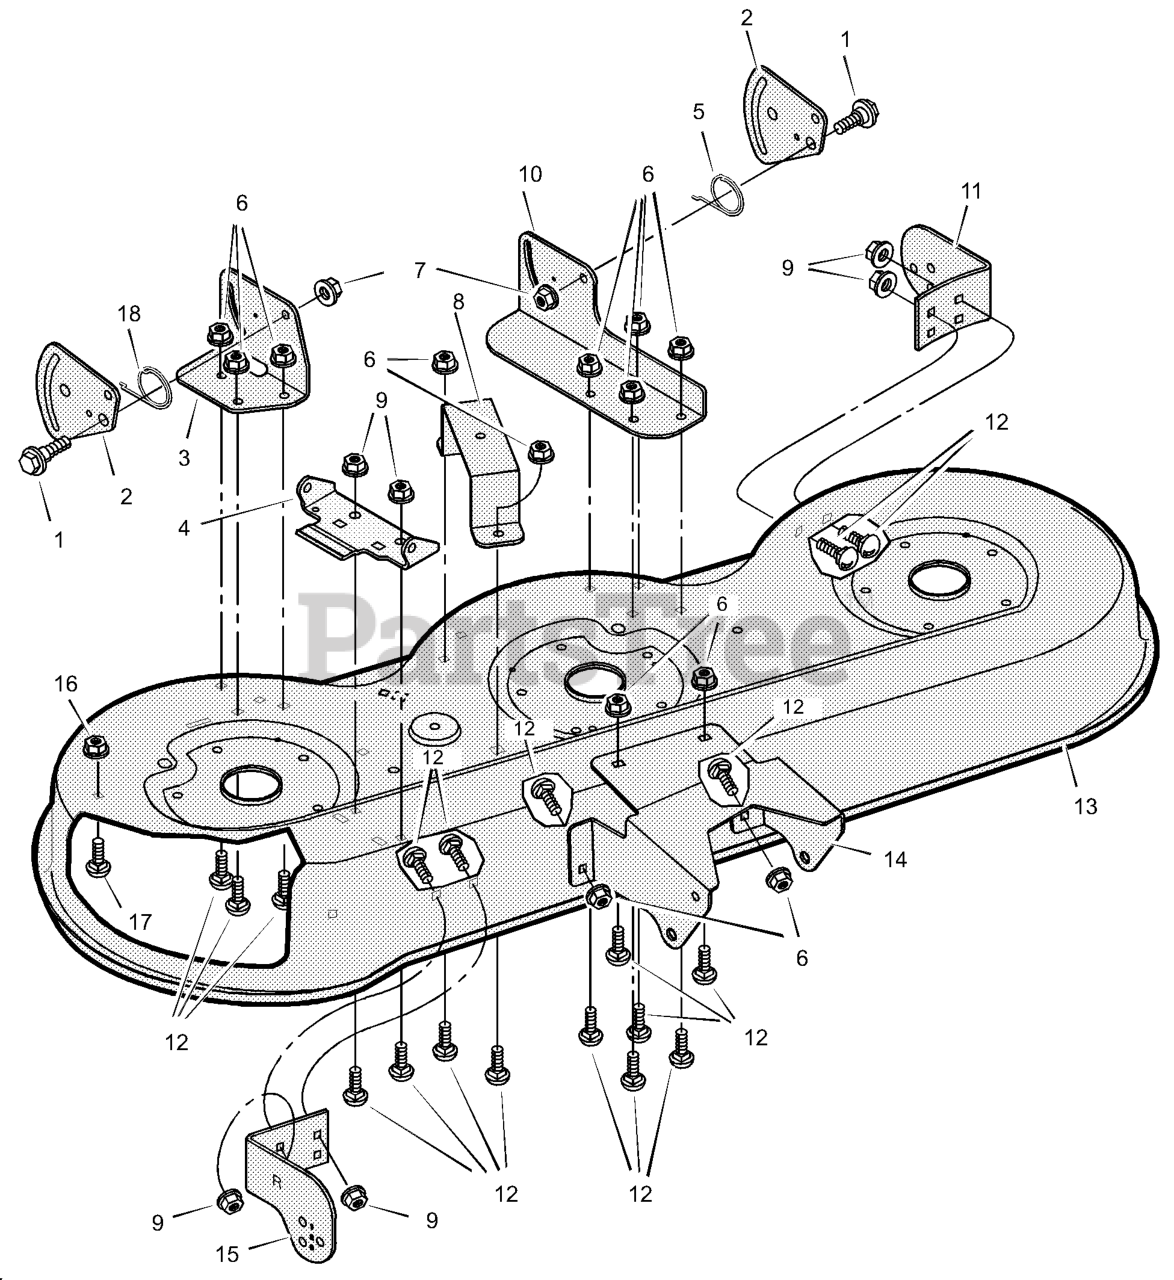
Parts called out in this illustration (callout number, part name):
1	Bolt, Shoulder
2	Plate, Suspension
3	Bracket, Right Rear
4	Bracket, Hinge
5	Spring, Left
6	Nut, Flange
7	Nut, Flange
8	Bracket, Bell Crank
9	Nut, Flange
10	Bracket, Left Lifter
11	Bracket, Left Gauge Wheel
12	Bolt, Carriage
13	Housing, Blade
14	Bracket, Front Deck
15	Bracket, Right Gauge Wheel
16	Retainer
17	Bolt, Carriage
18	Spring, Right
